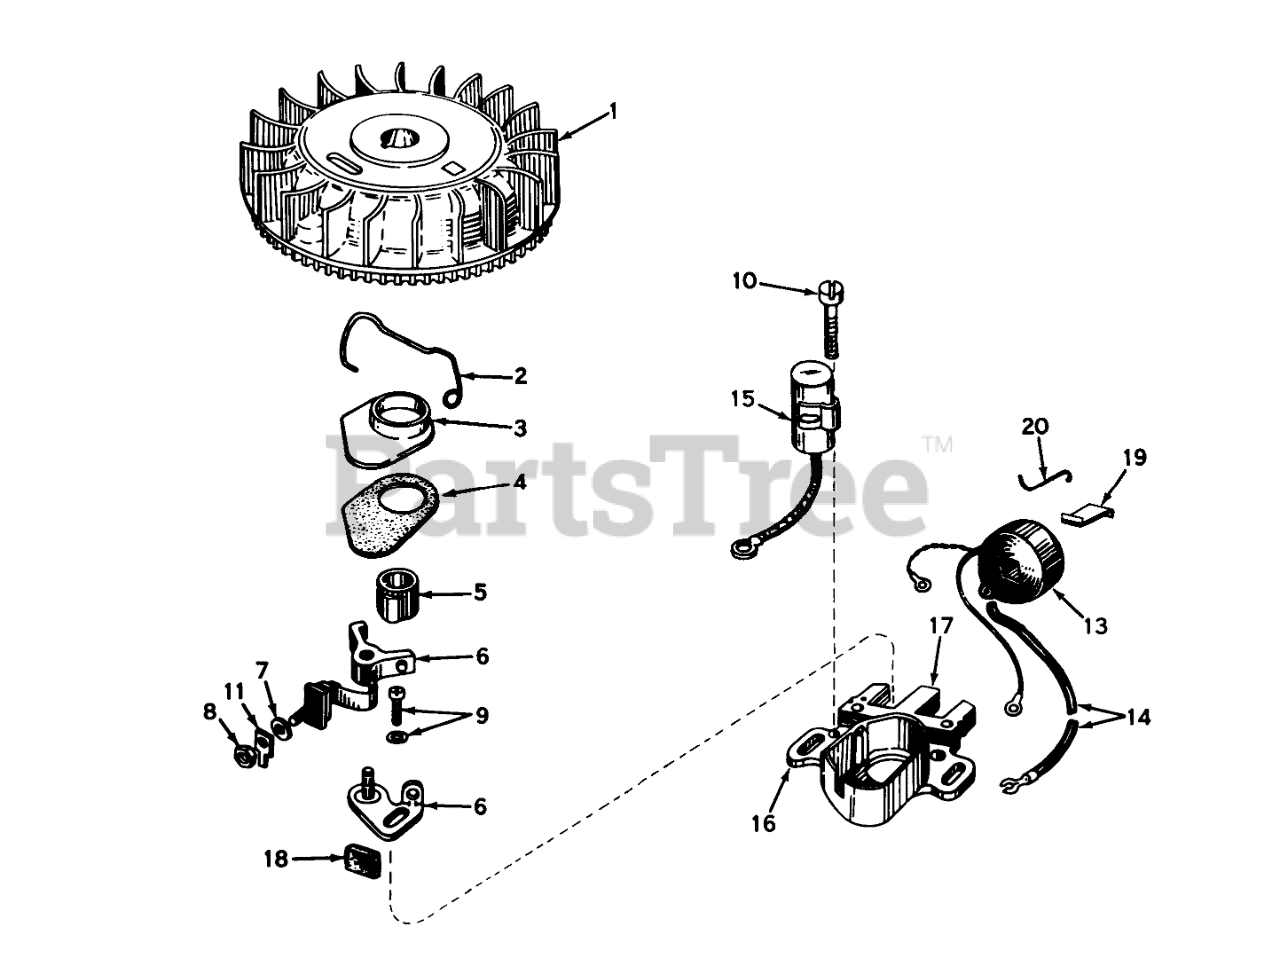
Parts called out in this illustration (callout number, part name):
1	FIywheel
2	Spring Breaker Box
3	Cover, Dust
4	Gasket Dust Cover
5	Cam, Breaker
6	Breaker Assy.
9	Breaker Screw
10	Condenser Screw
11	Terminal
13	Coil Assembly (Incl. No. 14)
14	Wire, Lead
15	Condenser
16	Core & Plate
17	Stator Assembly (Incl. Nos. 2, 3, 5 thru 14 & 16 thru 19)
18	Felt,Cam Wiper
19	Spring Coil Wedge
20	Clip, Coil
